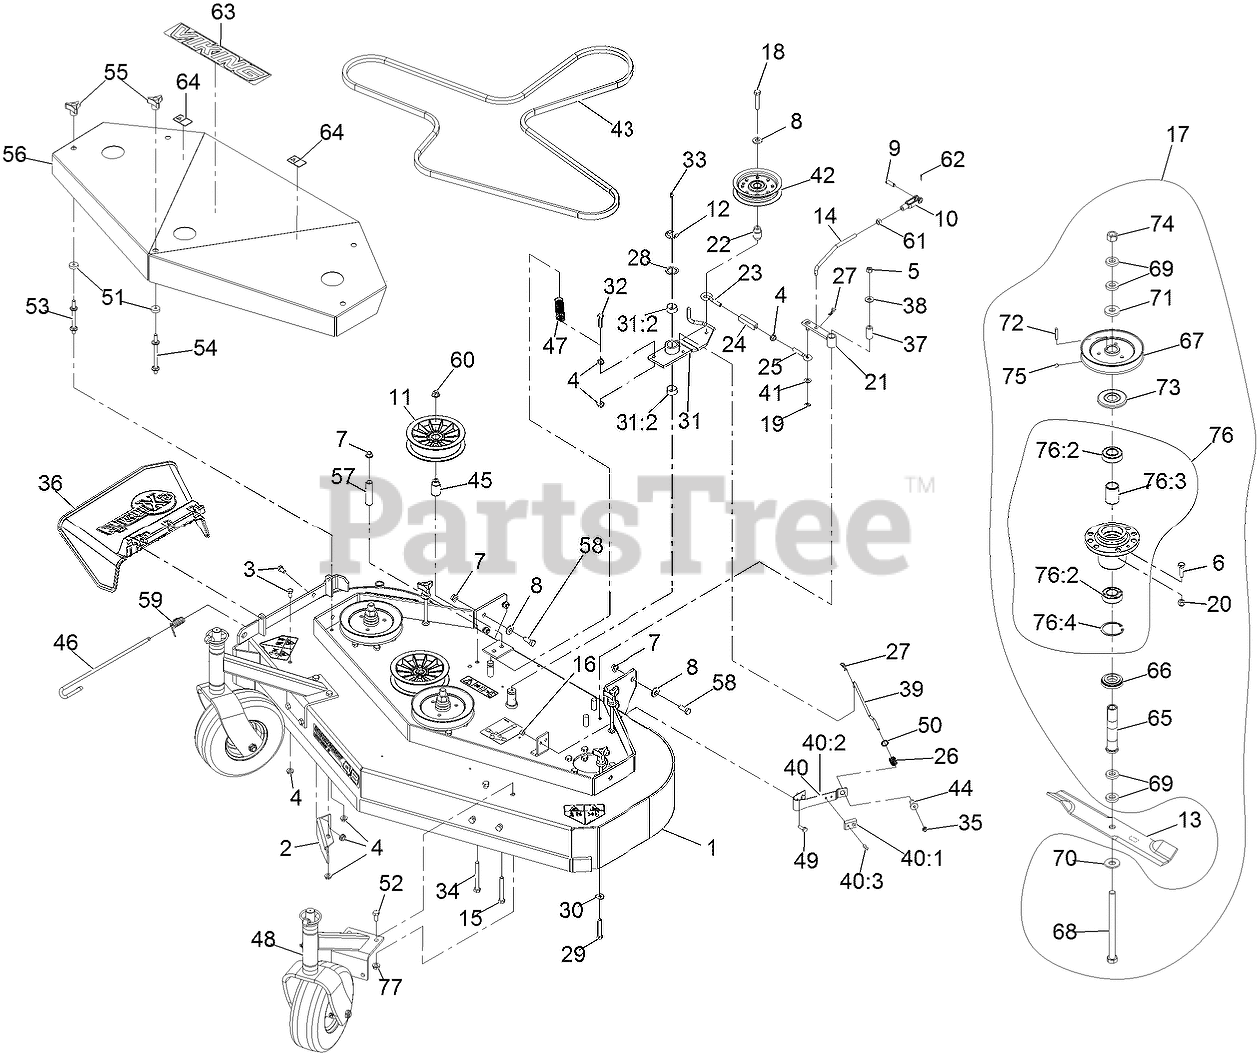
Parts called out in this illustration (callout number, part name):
1	DECK-SERVICE, 48
2	BAFFLE-DOGLEG
3	SCREW-HH
5	NUT-LOCK, NI
6	SCREW-HH
7	NUT-HHF, WHIZ
8	WASHER-BELLEVILLE
9	PIN-CLEVIS
10	YOKE-ADJUSTABLE
11	PULLEY,IDLER 5"
12	RING-RETAINING, EXT
14	ARM-LINKAGE, ASSIST
15	SCREW-HH
16	NUT-LOCK, NI
17	ASM, CUTTER HOUSING OUTER
18	SCREW-HH
19	RING-RETAINING, EXT
20	NUT-LOCK, NI
21	ARM-ASSIST, 32/36
22	BUSHING-ENGAGEMENT
23	EYEBOLT-THREAD, LH
24	BODY-TURNBUCKLE
25	EYEBOLT-THREAD, RH
26	SPRING-COMPRESSION
27	PIN-COTTER
28	WASHER-SPINDLE
29	SCREW-HH
30	WASHER-SPRING
31	IDLER ARM ASM
31:2	SLEEVE-BEARING
32	SCREW-HH, SPECIAL
33	FITTING-GREASE
34	SCREW-HH
35	NUT-LOCK, NI
36	CHUTE DEFLECTOR XRK M056
37	TUBE-PIVOT
38	WASHER-FLAT
39	ROD-BRAKE
40	PAD AND SPRING ASM
41	WASHER-PLAIN
43	BELT,BLADE 48
44	SPACER-FLANGED
45	BUSHING-IDLER
46	PIN-CHUTE
47	SPRING-EXTENSION
48	ASM-CASTER MNT W/WEIGHT
49	SCREW-HH
50	RING-PUSH ON
52	SCREW-HH
53	STUD-SHIELD, BELT (SHORT)
54	STUD-SHIELD, BELT (LONG)
55	KNOB-3 PRONG
56	ASM,SHIELD W/DECALS 48 VI
56	Shield Weldmt, 48"
58	SCREW-HH
59	SPRING, TORSION
60	NUT-HF, NI
61	NUT-HEX
62	PIN-COTTER
63	DECAL, VIKING HYDRO MODEL
64	DECAL-WARNING
65	TUBE-SPINDLE, SHORT
66	SPACER-GUARD, BOTTOM
67	SHEAVE
68	SCREW-CAP, HH
70	WASHER-SPRING
71	WASHER-RETAINER, SHEAVE
73	GUARD-BEARING, TOP
74	NUT-HEX
75	SETSCREW
76	Cutter Housing ASM
76	KIT, CUTTER HOUSING
76:2	BEARING-JACKSHAFT
76:3	SPACER-BEARING
76:4	RING-SNAP
77	NUT-HHF, WHIZ
